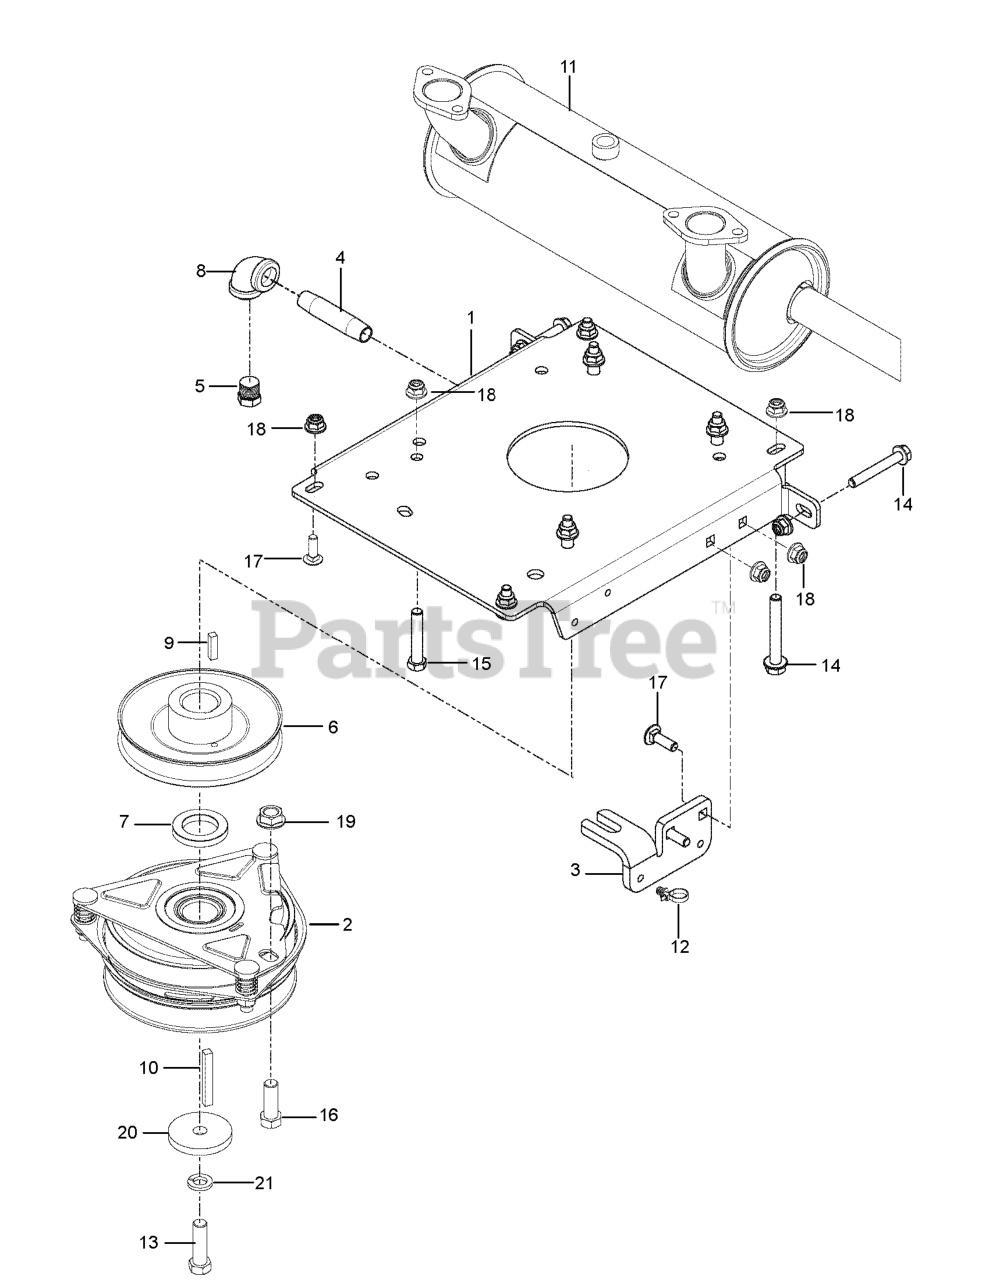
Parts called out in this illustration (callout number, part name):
1	PLATE.PNT.ENGINE.PZ/PZT.EDIP
2	CLUTCH, 150 FT/LBS
3	STOP, CLUTCH, OGURA
4	PIPE NIPPLE 3/8 X 3
5	PLUG, DRAIN 3/8 NPTF
6	PULLEY, ENGINE
7	SPACER, .25 X 1.135 I.D.
8	90 DEG.ELBOW 3/8NPT
9	KEY 1/4 SQ X 1.0
10	KEY 1/4 SQ X 2
11	MUFFLER.KOH.EFI.W/O2.SENSOR
12	TIE WRAP, 8-3/8", W/CLIP
13	CLUTCH BOLT7/16-20X1.5GR5.96HR
14	HHFS 5/16-18 X 2.25 GD 5
15	HHFS 5/16-18 X 1.5 GD 5
16	HCS 7/16-14 X 1-1/4 GR 5 ZD
17	RHSNB 5/16C X 1
18	5/16-18 NYLOC FLANGE NUT
19	NUT 7/16C WHIZ
20	BLADE WASHER
21	WASHER 7/16 LOCK
